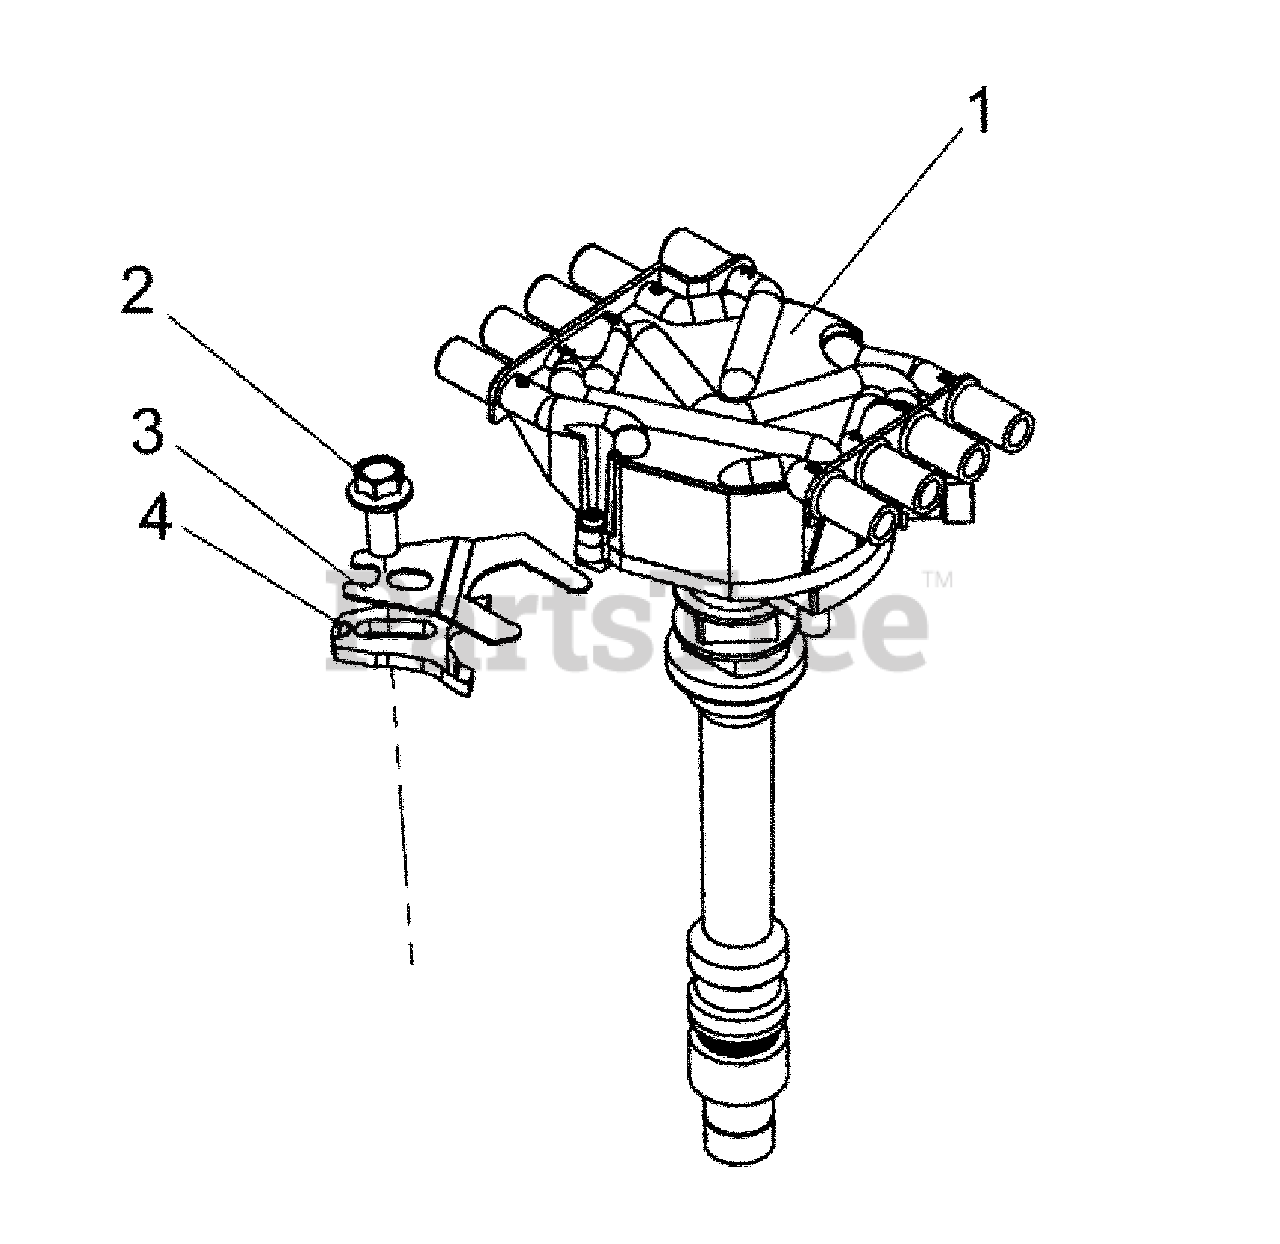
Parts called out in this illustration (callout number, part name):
1	DISTRIBUTOR ASSEMBLY
2	SCREW
3	BRACKET
4	CLAMP
